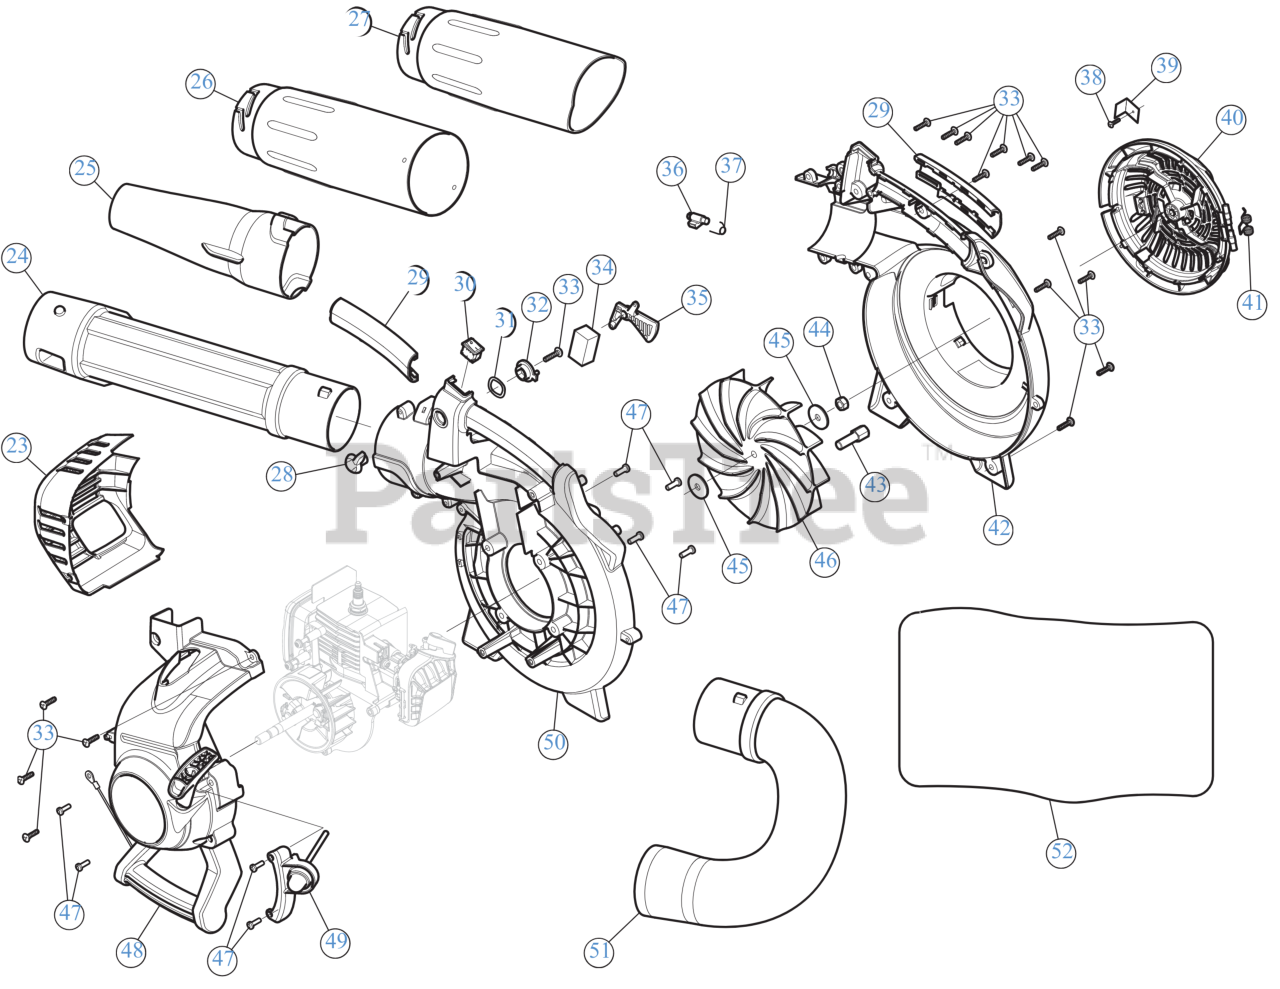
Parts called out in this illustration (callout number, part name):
23	MUFFLER COVER
24	UPPER TUBE
25	NOZZLE BKPK CUB
26	UPPER VAC TUBE SCBLO
27	TUBE, LOWER VACUUM (ELEC BLWR-
28	TRIGGER LOCK OTR
29	ANDLE GRIP ASSEMBLY
30	SW, MOMENTARY ON/O
31	WASHER WAVEY
32	TRIGGER LOCK INR
33	SCREW 8-16 x 3/4
34	AIR FILTER
35	THROTTLE TRIGGER
36	LATCH TUBE
37	SPRING LATCH
38	SCREW-10-9 x .50
39	DOOR LOCK SC
40	INTAKE COVER
42	IMPELLER HOUSING OTR
43	ADAPTER STARTER
44	HEX NUT CENTER
45	WASHER FLAT
47	SCREW:10-32X.562:#8P
48	STARTER HOUSING
49	REMOTE PRIMER BRACKET
50	IMPELLER HOUSING INR
51	ELBOW TUBE
52	VAC BAG SCBLO
